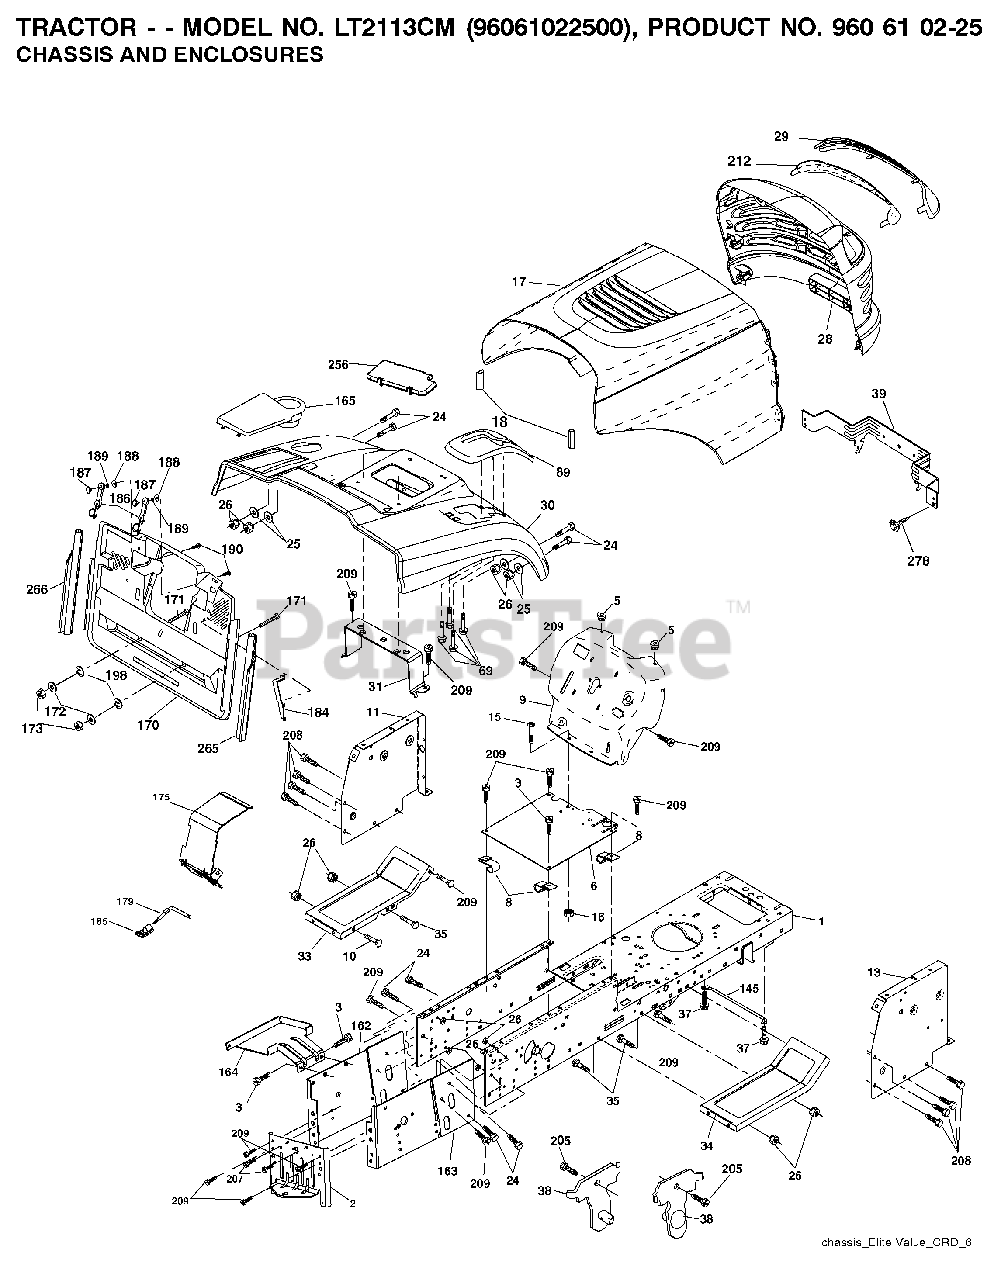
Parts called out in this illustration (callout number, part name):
1	CHASSIS
3	SCREW 3/8-16X3/4
5	BUMPER.RUBBER.HOOD
8	CLIP,INSULATOR
10	BOLT D
11	PANEL.DASH.LH.LTX
13	PANEL DASH RH
16	NUT
18	BUMPER.HOOD.LARGE.1.75"
25	WASHER
26	NUT
31	BRACKET SUPPORT FENDER
39	BRACKET PIVOT
69	SCREW.HI-LO.CONSOLE
145	ROD.PIVOT.HOOD
164	SUPPORT
171	BOLT
172	WASHER
186	LATCH ASSY
187	WELDNUT
189	LOCKWASHER
207	SCREW, 5/16-18 X 1/2
208	SCREW 3/8-16X1/2
209	SCREW, 3/8-16X3/4
278	SCREW
